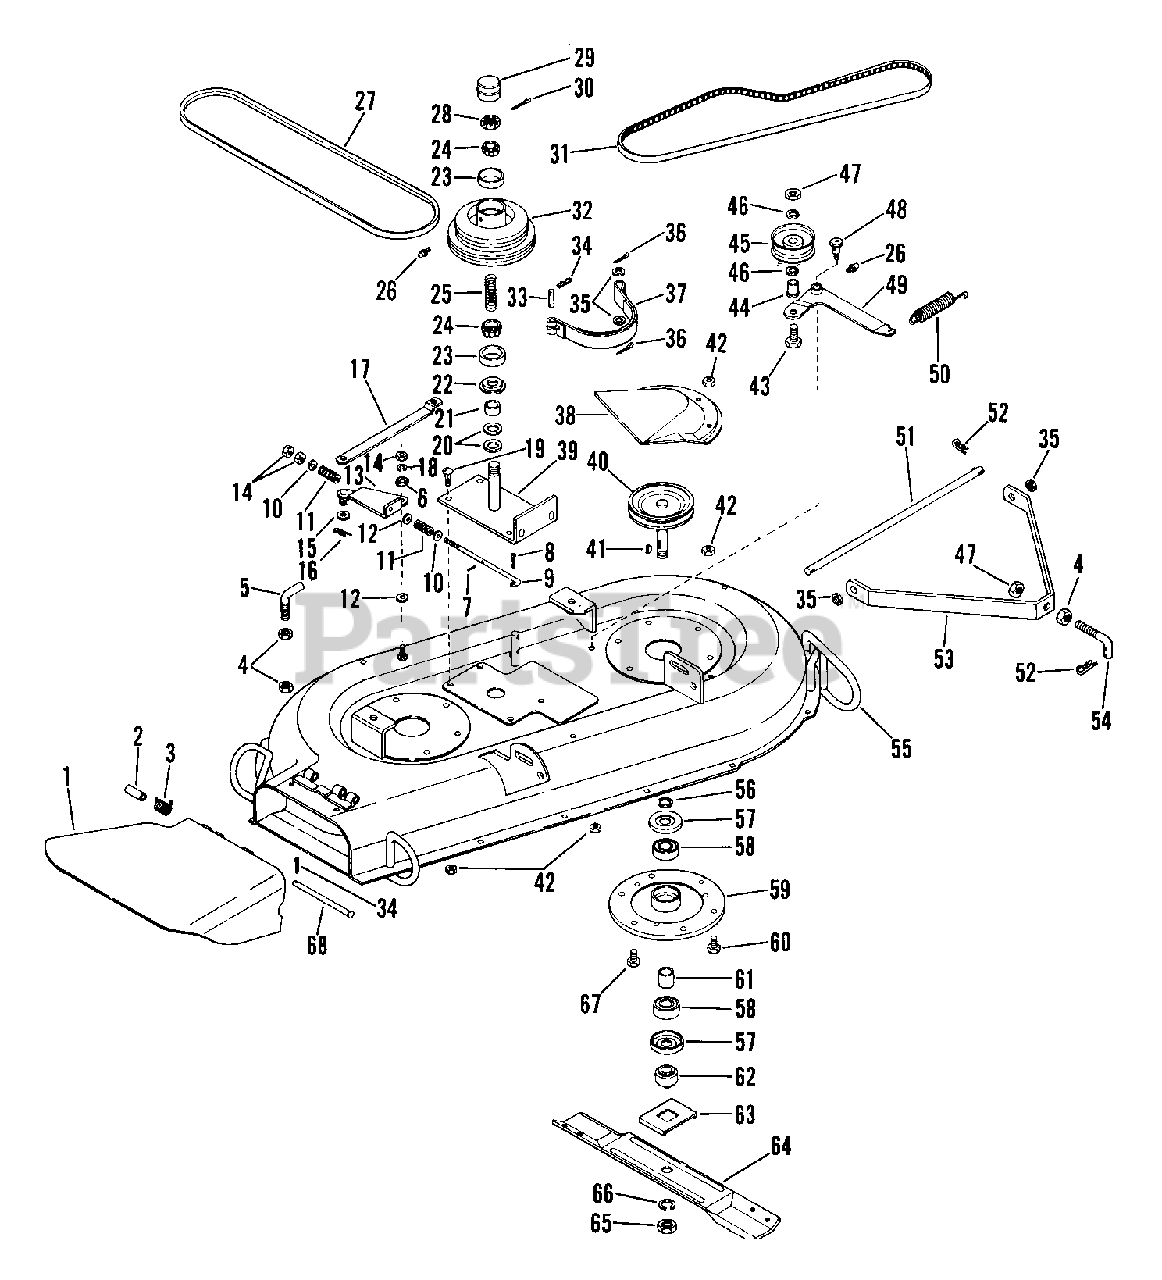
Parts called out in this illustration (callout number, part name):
1	CHUTE DEFLECTOR UNIT
2	BSHG-SLV .334 X .502 X 1.437
3	SG-TORS .095X.50X 1.0
4	NUT-JAM .50-13 PL
5	HANGER HOOK
6	SPACER -FLANGED .325X.498X.318
7	PIN-ROLL .125X.75
8	PIN-COTR .06X.50
9	BRAKE ROD
10	WSHR-FL-STL .323X.625X.062 PL
11	SG-COMP .057X.47X1.25
12	WSHR-FL-STL .38X.875X.083 PL
13	BRAKE LEVER
14	NUT-LK .312-18 GR A PL
15	WSHR-FL-STL.406X.812X.065PL
16	PIN-HAIR INT .08X.38X1.42 YWZC
17	LINK
18	WSHR-LK .44 SP HEAVY
19	BLT-RDHDSQNK .38-16X.75 SHT PL
20	WSHR-FL-STL .755X1.375X.062 PL
21	SPACER .753X1.000X.625
22	SEAL .750X1.690X.153
23	BRG-CUP 1.781X.475
24	BRG-CONE .750X.61
25	SG-COMP .091X.950X2.062
26	SPIN DRIVE ZERK FITTING
27	V-BELT, 4L-RAW EDGE
28	NUT-JAM SL .75-20 PL
29	CAP, GREASE
30	PIN-COTR .12 X 1.25 PL
31	V-BELT, 4L-RAW EDGE
32	SHEAVE 38 IN PAN
33	CLEVIS PIN
34	PIN-COTR .09X.75 PL
35	WSHR-FL-STL .505X.880X.072 PL
36	PIN-COTR .09X1.0 PL
37	BRAKE BAND
40	SHEAVE
41	KEY-WDRF .188X.75X.313 SAE 9
42	NUT-LK-CTR .375-16 GR A PL
43	BLT-HEX .50-13X1.25 PL GR2
44	BSHG-FLG .500X.625X.500X.750
45	IDLER-FLAT 2.75X.62
46	WSHR-FL-STL .520X.810X.033
47	NUT-LK-CTR .50-13
48	SHOULDER BOLT .50 X 1.00
50	SG-TENS .112X.89X5.28 WLD 56
51	TOW PIN
52	PIN-HAIR INT .09X.188 PL
53	MOWER STRAP
55	38 INCH MOWER PAN W/DECALS
55	38 INCH MOWER ASSEMBLY
56	WSHR-FL-STL .755X1.250X.125
57	BEARING SLINGER
58	BRG-BALL .750X1.781X.61
59	SPINDLE HOUSING
60	BLT-HEX .38-16X.75 PL GR2
61	SPACER .753X1.000X1.140
62	RETAINER HUB
63	BLADE TRAY
64	MOWER BLADE
65	NUT-JAM .75-10 PL
66	WSHR-LK .750X.188 MED PL
67	BLT-HEX .38-16X1.00 PL
68	CLEVIS PIN
